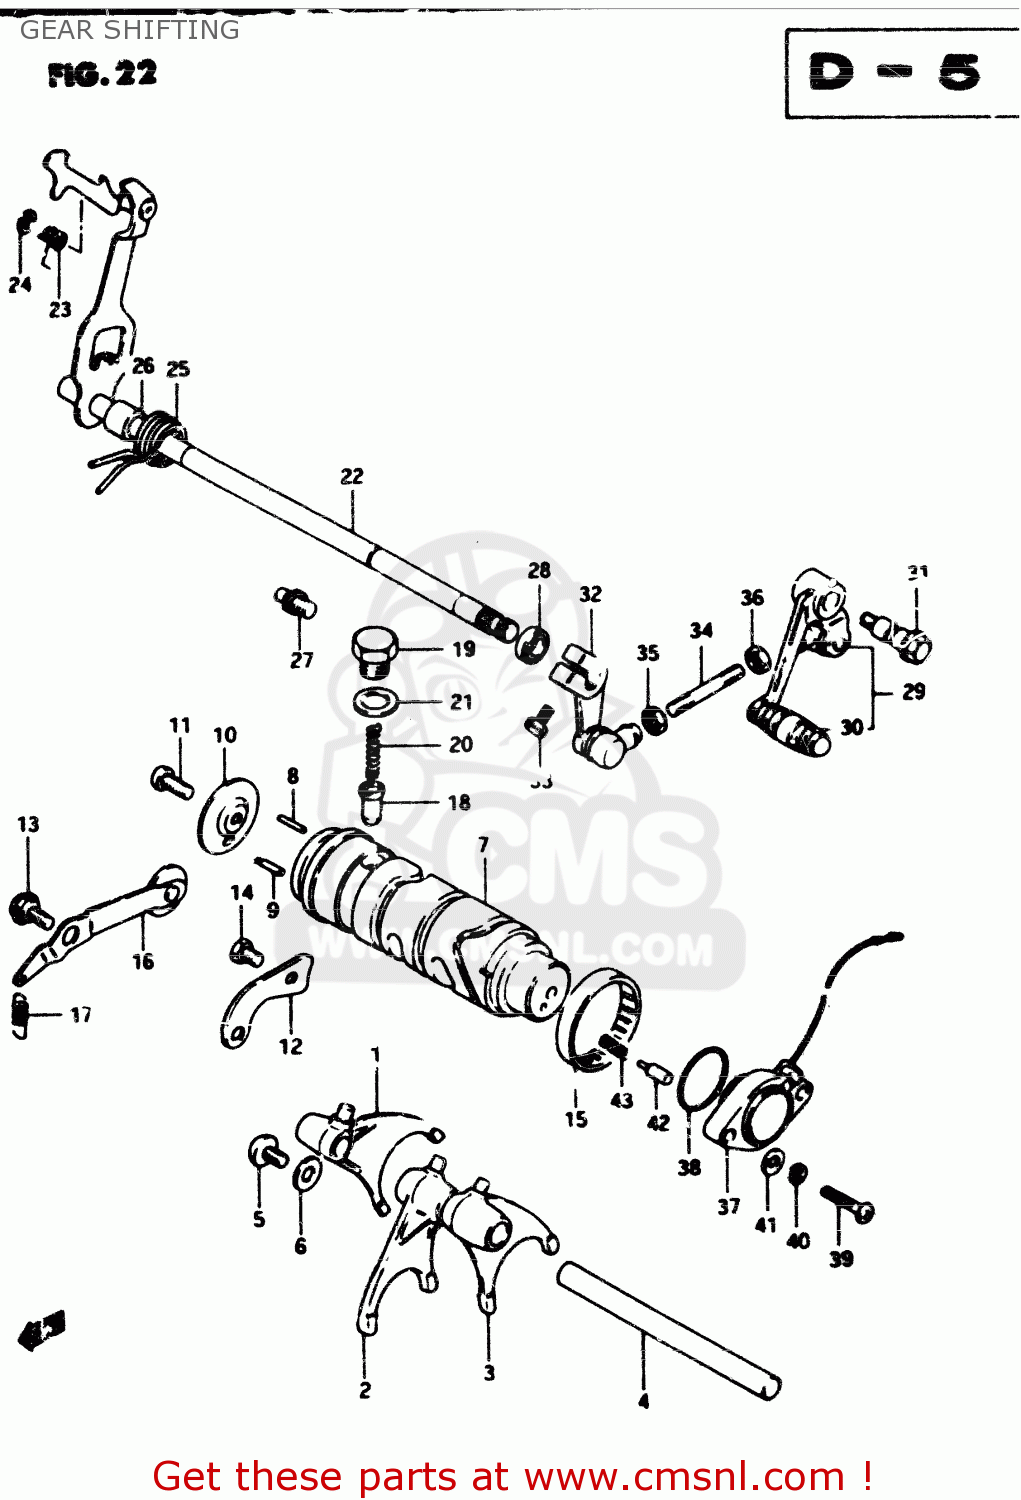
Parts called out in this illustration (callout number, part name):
1	FORK,GEAR SHIFT NO.1
2	FORK,GEAR SHIFT NO.2
3	FORK,GEAR SHIFT NO.3
4	SHAFT,GEAR SHIFT FORK
5	SCREW
6	WASHER
7	CAM,GEAR SHIFT
8	PIN(4X18.5)
9	PIN
10	RETAINER,GEAR SHIFT CAM DR PIN
11	SCREW
12	GUIDE,GEAR SHIFTING CABLE
13	BOLT
14	BOLT, UPPER
15	BEARING(40X47X12)
16	STOPPER,GEAR SHIFTING
17	SPRING
18	STOPPER,GEAR SHIFT CAM NO.2
19	HOLDER,GEAR SHIFT CAM STOP SPR
20	SPRING
21	GASKET(14X19.2X2) (NAS)
22	SHAFT,GEAR SHIFT
23	SPRING
24	E RING
25	SPRING
26	SPACER(12X20X15.3)
27	STOPPER,GEAR SHIFT CAM
28	OIL SEAL
29	LEVER ASSY,GEAR SHIFT
30	RUBBER,GEAR SHIFT PEDAL
31	SHAFT,GEAR SHIFT LEVER
32	ARM,GEAR SHIFT LINK
33	BOLT
34	ROD,GEAR SHIFT LINK
35	NUT
36	NUT
37	TERMINAL BASE,NEUTRAL SWITCH
38	O-RING (D:2.4 ID:26.2)
39	SCREW 5X20
40	LOCK WASHER
41	WASHER
42	PIN(5X15.5)
43	SPRING
